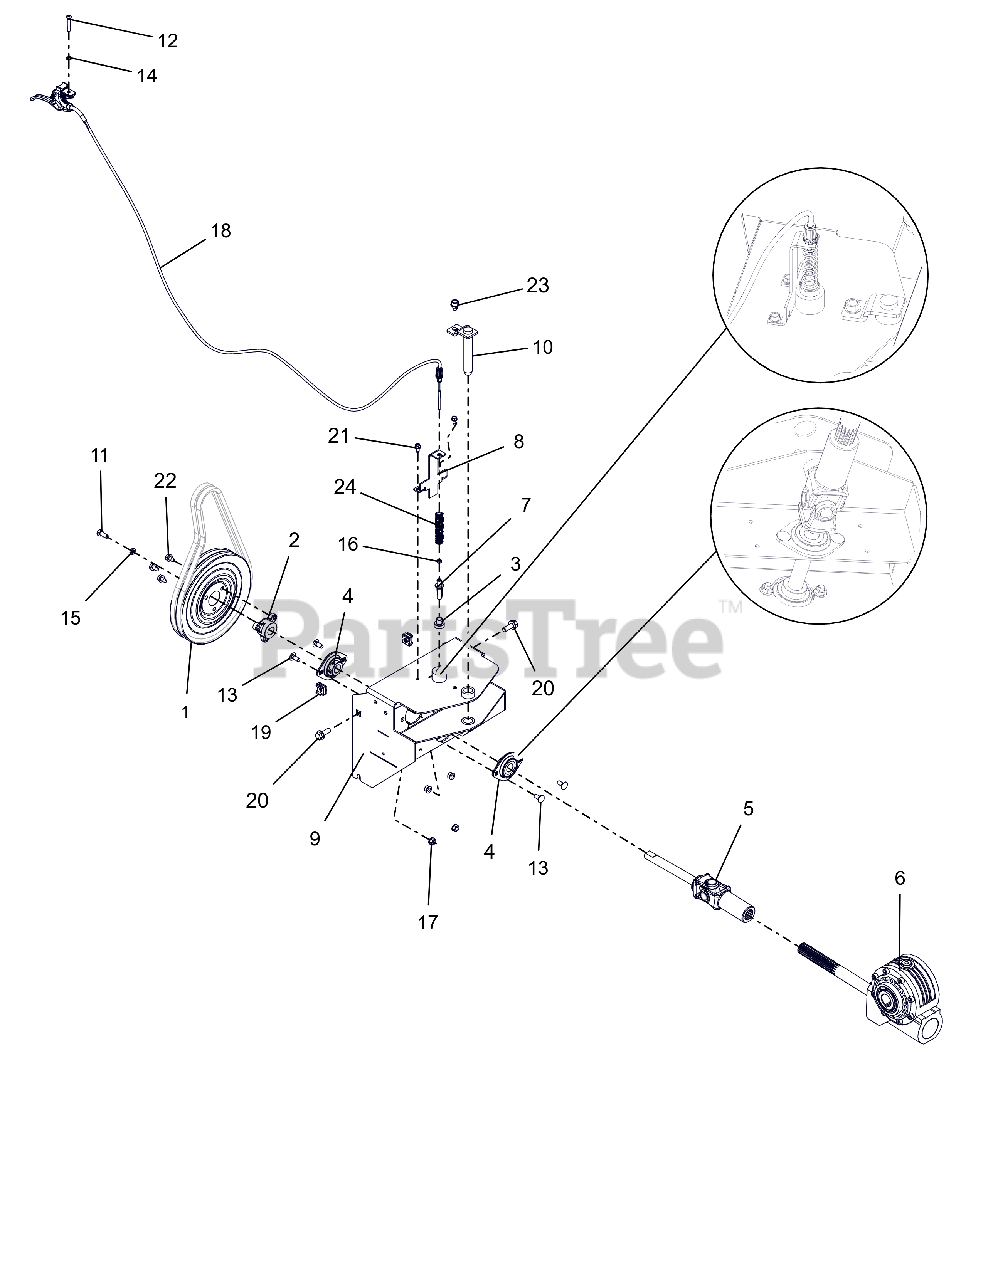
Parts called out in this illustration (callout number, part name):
1	PULLEY, SPIN FORM DUAL GROOVE
2	PULLEY HUB, BOLT-ON D-BORE .75
3	SPACER -FLANGED .390X.500X.781
4	BEARING, 2 BOLT FLANGE -.75 ID
5	DRIVELINE, SERIES 07 (U-JOINT)
6	GEARBOX, WORM - 8.25:1
7	PIN, ADJUSTABLE ANGLE BRUSH
8	BRKT, PIN HOLDER
9	ADAPTER, BRUSH
10	WLDMT, BRUSH PIN
11	BLT, HEX .31-24X.750 G5 ZCC
12	SCR-MCH .25-20X1.50 OVAL HD
13	BLT,RHSN .31-18X.75 G5 ZCC
14	WSHR-LK-INT .250 TH TYA
15	WSHR, LK-HVY .312X.097 ZCC
16	NUT, HEX #10-24 ZCC
17	NUT-LK-TOP-FLG .312-18 GF ZCC
18	CABLE, REMOTE BRUSH LOCK
19	NUT-RETNR .38-16 TINRMAN
20	BLT, SERHFWH .38-16X1.00 ZCC
21	SCR-TAP .25-20X.50 HWH ZCC
22	SCR,TAP .312-18X.50 HWH TR ZCC
23	SCR,TAP .375-16X.50 HWH TR ZCC
24	SPRING, COMPRESSION
